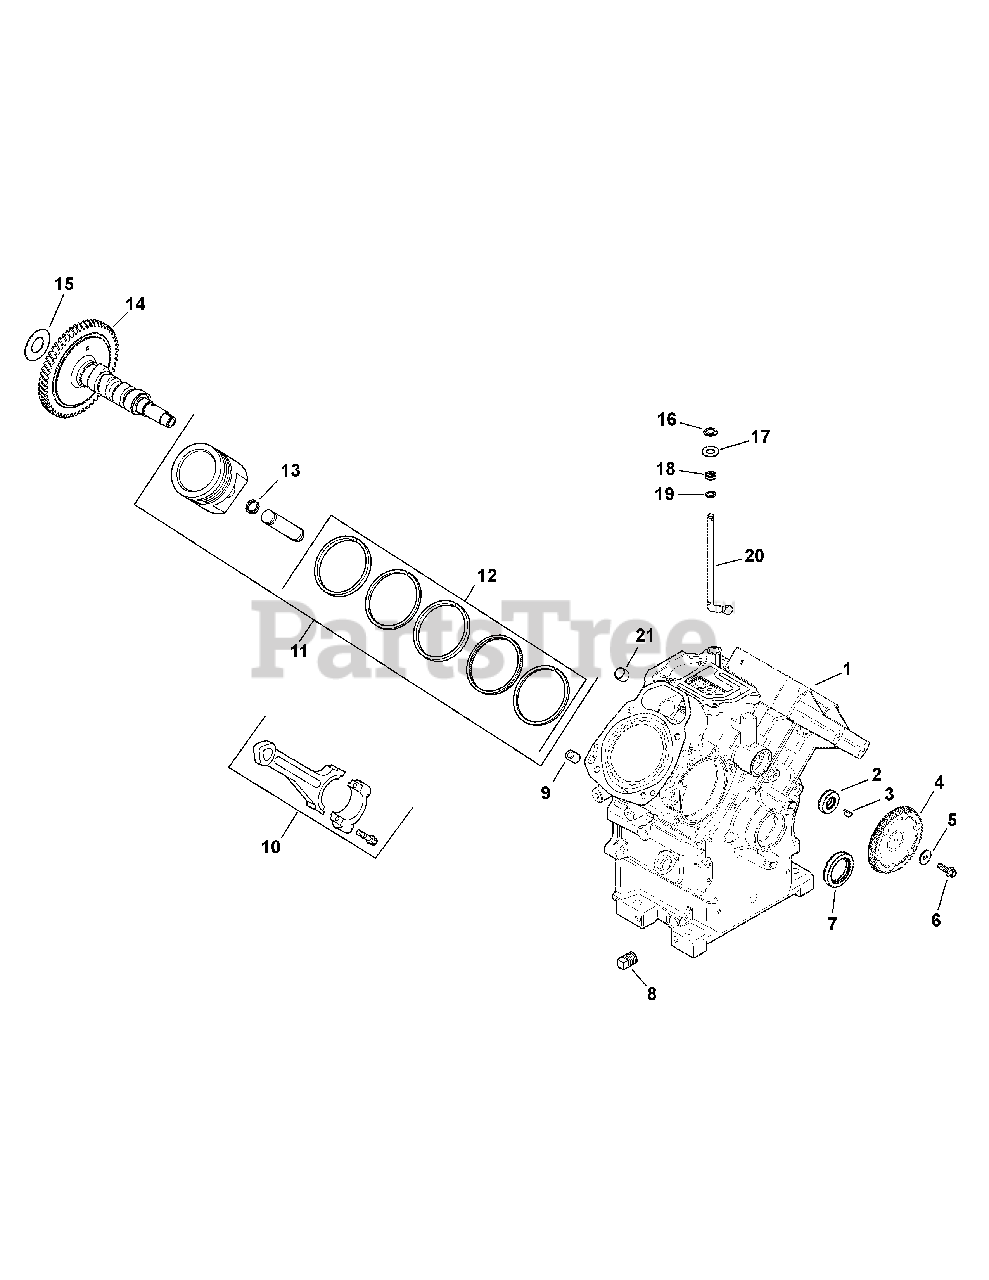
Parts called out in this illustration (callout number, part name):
1	Crankcase
2	Seal, Camshaft
3	Key, 3/32" x 3/8"
4	Sprocket, Camshaft
5	Washer, Flat 1/4"
6	Screw, Flg, M6 x 1.0 x 20
7	Seal, Oil (Helix Lip)
8	Plug, Sq Hd Pipe, 3/8"
9	Pin, LoYanmaring
10	Connecting Rod (Std)
10	Connecting Rod (.25)
11	Kit, Piston w/Ring Set
11	Kit, Piston w/Ring Set (.08)
12	Ring Set (Std)
12	Ring Set (.08)
13	Retainer, Piston Pin
14	Kit Camshaft - EFI
15	Shim, Camshaft (White .028")
15	Shim, Camshaft (Blue .03")
15	Shim, Camshaft (Red .032")
15	Shim, Camshaft (Yellow .034")
15	Shim, Camshaft (Green .036")
15	Shim, Camshaft (Gray .038")
15	Shim, Camshaft (Black .04")
16	Retainer, Ring
17	Washer, Flat 9 mm
18	Seal, Governor Cross Shaft
19	Washer, Flat, 11/32"
20	Shaft, Governor Cross
